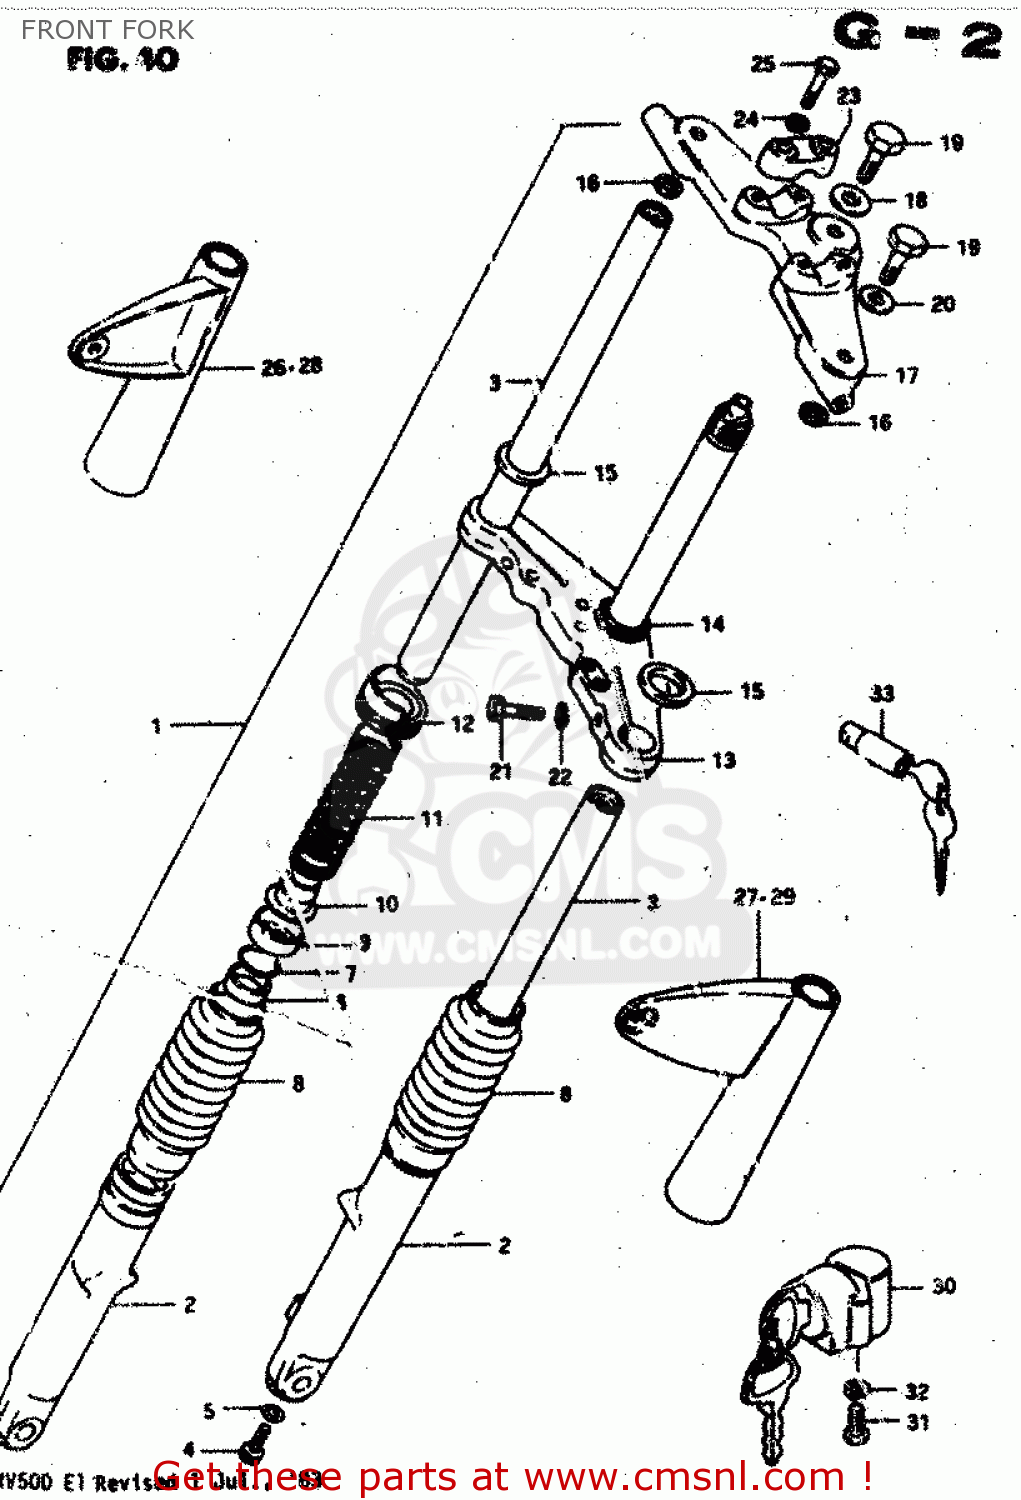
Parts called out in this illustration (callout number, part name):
1	FORK ASSY, FRONT
2	OUTER TUBE
3	INNER TUBE
4	BOLT
5	GASKET (NAS)
6	SEAL,OIL
7	RING,OIL SEAL STOPPER
8	BOOT
9	SEAT, SPRING
10	GUIDE, SPRING
11	SPRING
12	COVER,STEERING STEM
13	STEERING STEM
14	RACE,STEERING OUTER LWR
15	CUSHION
16	O RING
17	HEAD, STEERING STEM
18	WASHER,STEM HEAD(10.5X30X3.2)
19	BOLT,FORK INNER TUBE
20	WASHER
21	BOLT
22	LOCK WASHER
23	HOLDER,HANDLE UPR
24	LOCK WASHER
25	BOLT
26	COVER, UPPER RH
27	COVER, UPPER LH
28	COVER, UPPER RH
29	COVER, UPPER LH
30	LOCK ASSY,STEERING
31	SCREW
32	LOCK WASHER
33	LOCK ASSEMBLY,STEERING (NEI
